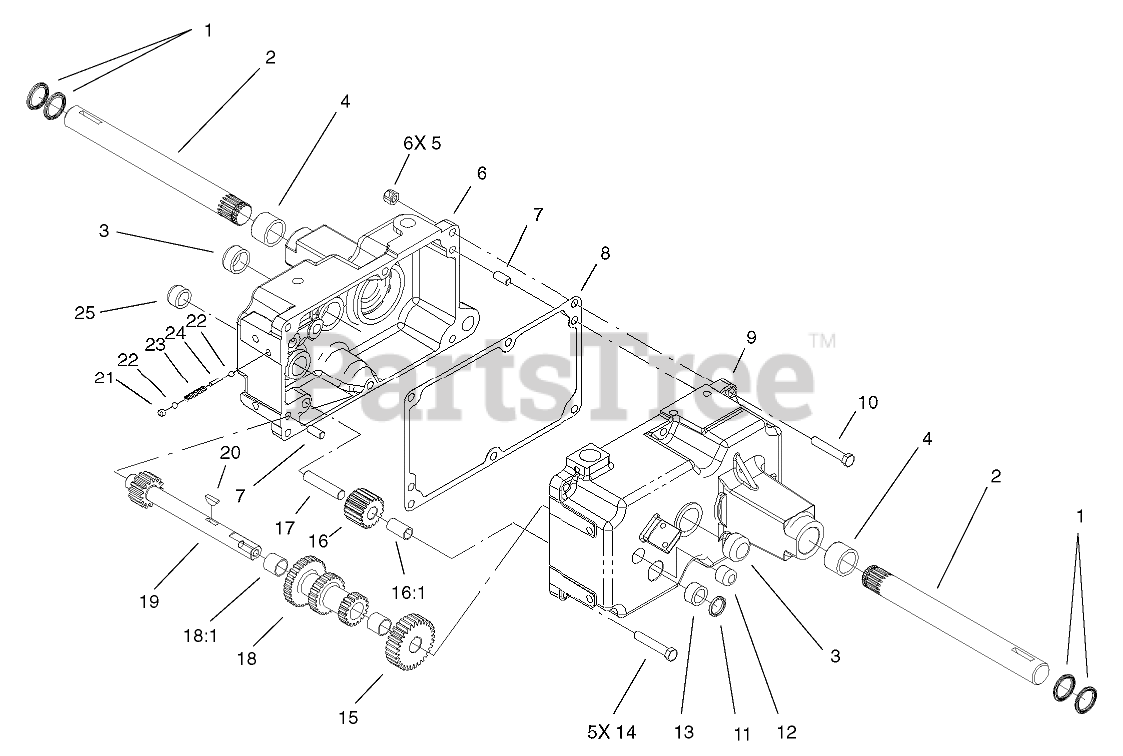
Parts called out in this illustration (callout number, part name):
1	SEAL-OIL
2	AXLE-REAR
3	BEARING-NEEDLE
4	BEARING
5	NUT-LOCK, NI
6	CASE-RH TRANS
7	PIN-DOWEL
8	GASKET-TRANSMISSION
9	CASE-TRANS LH
10	SCREW-HH
11	SEAL-OIL
12	BEARING-NEEDLE
13	BEARING-NEEDLE
14	SCREW-HH
15	GEAR-CLUSTER SHAFT
16	GEAR/BUSHING ASM-REVERSE IDLER
17	PIN-DIFFERENTIAL
18	GEAR-CLUSTER
19	SHAFT-CLUSTER
20	KEY-WOODRUFF
21	CUP-PLUG
22	BALL-DETENT
23	SPRING-SHIFT STOP
24	PIN-SHIFT
25	BEARING-NEEDLE
